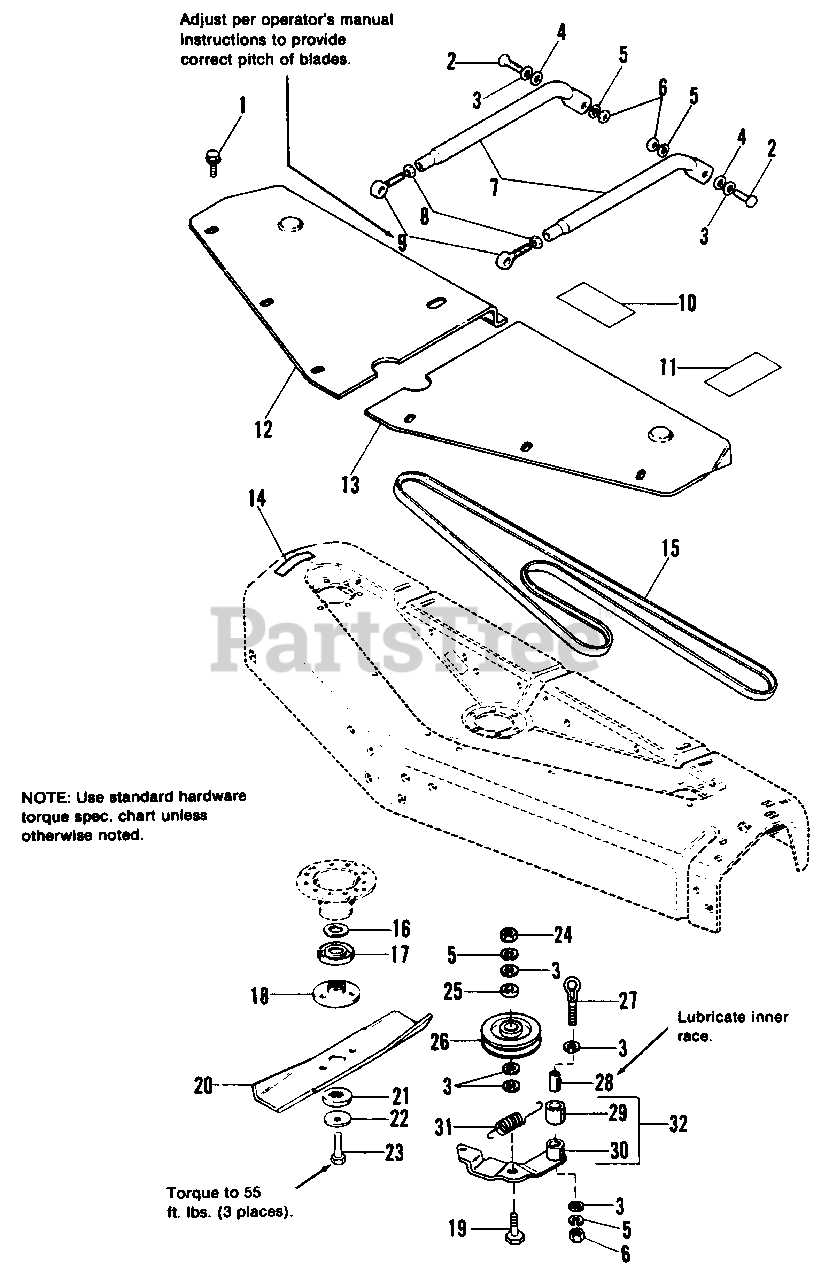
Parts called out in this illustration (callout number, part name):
1	SCREW, Hex, Taptite, 1/4-20 x 3/8
2	CAPSCREW, Hex Hd., 3/8-16 x 1
3	WASHER, Plain, 5/16
5	LOCKWASHER, 3/8
6	NUT, Hex, Full, 3/8-16
7	ARM, Adjusting
8	NUT, Hex, Jam, 1/2-20
10	DECAL, Belt Installation
11	DECAL, Danger
12	COVER, R.H.
13	COVER, L.H.
14	DECAL, Danger
15	BELT, "V" Arbor Drive
16	WASHER, Shim
17	SHIELD, Grass
18	ADAPTOR, Blade
19	CAPSCREW, Hex Hd., 3/8-16 x 1-1/4
20	BLADE, 42" Mower
21	WASHER, Spline
22	WASHER, Spring
23	CAPSCREW, Hex Hd., 7/16-14 x 1
24	NUT, Hex, Jam, 3/8-16
26	PULLEY ASSY.
28	RACE, Inner
32	LEVER ASSY., Idler (w/Bushing)
